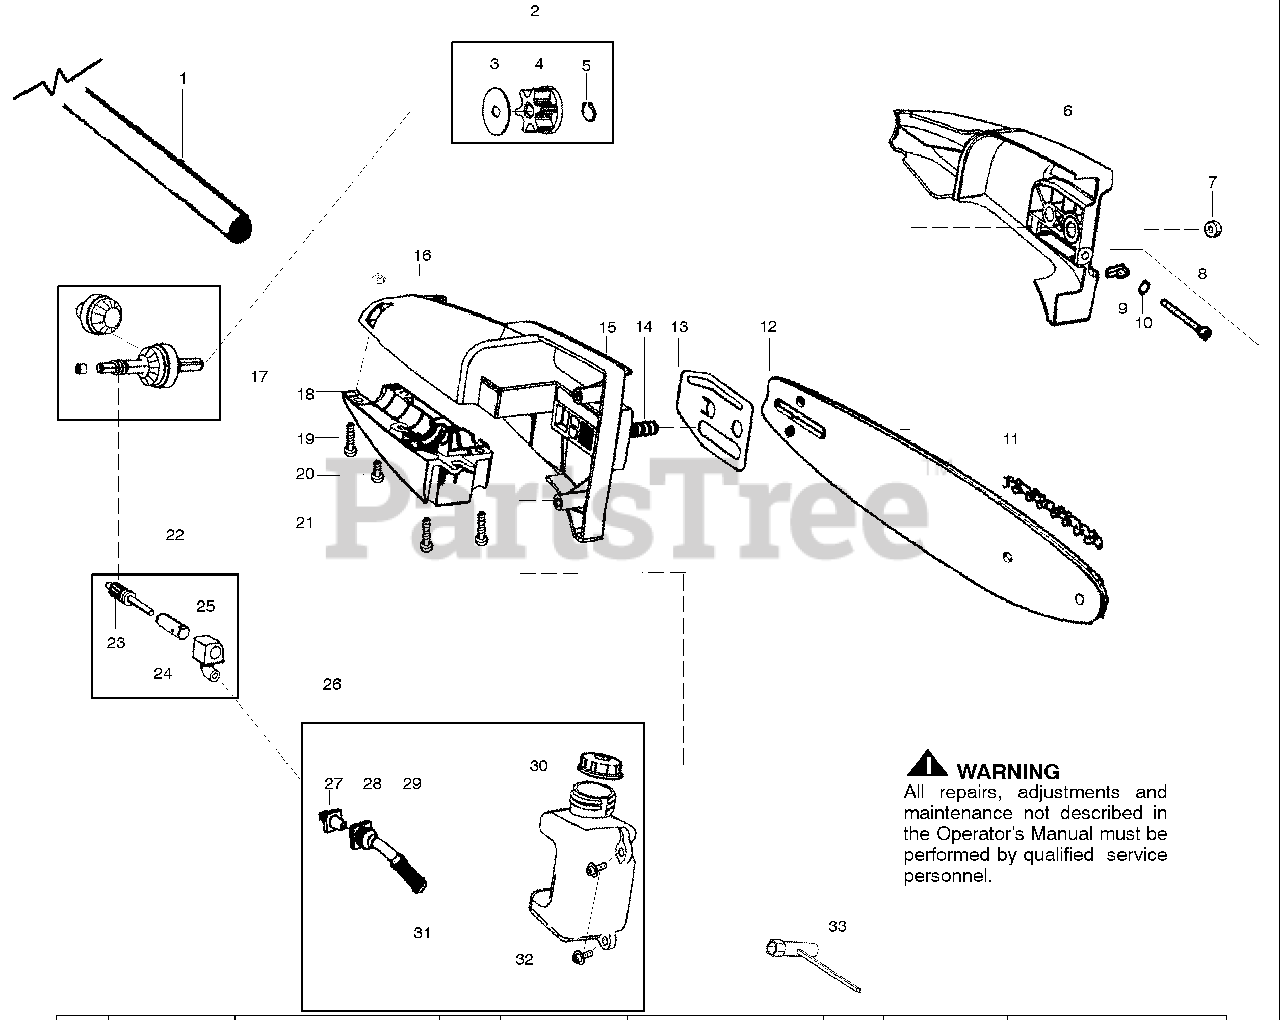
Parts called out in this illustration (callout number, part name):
1	Assy-Driveshaft
2	Kit-Sprocket Assy.
5	Retainer-Sprocket
6	Assy-Bar Clamp
7	Nut-Bar Mounting
8	Kit-Bar Adjust
9	Pin-Bar Adjust
10	Retainer-Bar Adjust
11	Accy.-Chain-8"
13	Plate-Bar pad
15	Hsg.-Upper
17	Kit-Gear Assy
20	Screw-Align
22	Kit-Oil Assy
23	Assy-Gear Plunger
26	Assy-Oil Tank
27	Fitting-Oil Line
28	Intake-Oil Line
29	Filter-Oil
30	Cap-Oil
31	Plug-Oil Filter
